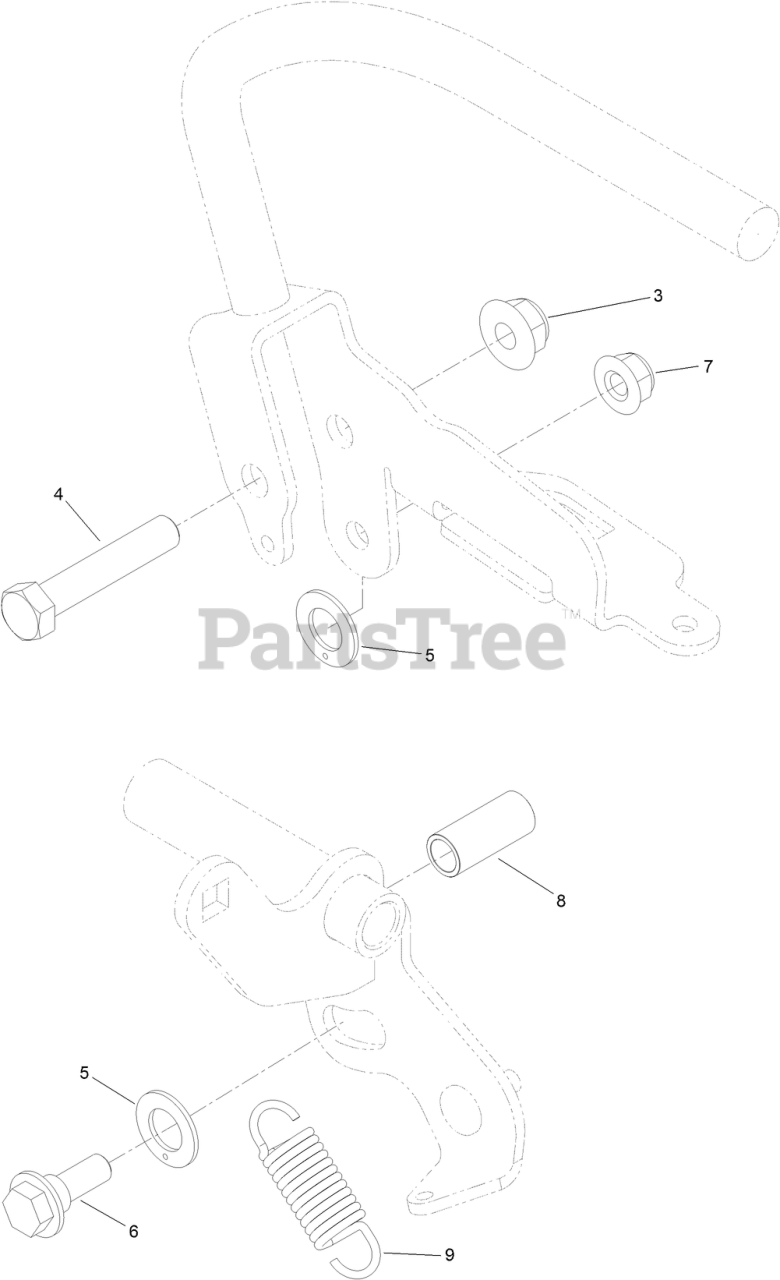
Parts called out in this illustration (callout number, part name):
3	NUT-HF, NI
4	SCREW-HH
5	WASHER-THRUST
6	SCREW-SHOULDER
7	NUT-HF, NI
8	BEARING-SLEEVE
9	SPRING-EXTENSION
